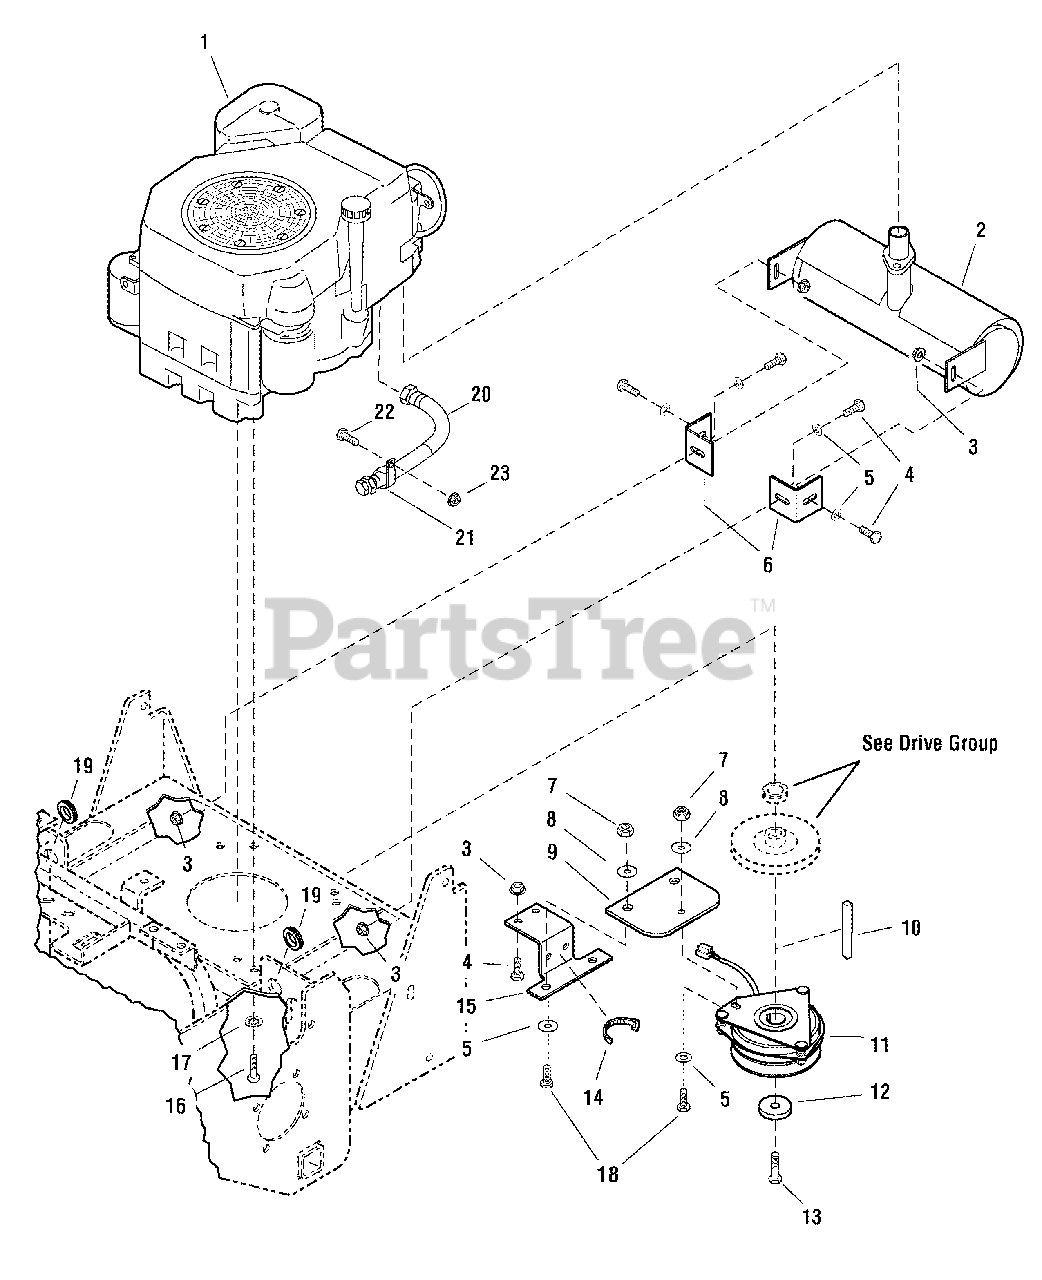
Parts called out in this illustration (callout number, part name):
3	NUT, Hex Serrated Flange, 5/16-18
4	CAPSCREW, Hex Head, 5/16-18 X 3/4
5	WASHER, SAE, 5/16
6	BRACKET, Muffler Support, Orange
6	BRACKET, Muffler Support, Red
7	NUT, Hex Nylon Lock, 5/16-18
8	WASHER, Clutch Anchor, 5/16
9	PAD, Clutch Anchor
10	KEY, 1/4 Square X 2-1/4
11	CLUTCH, Electric
12	SPACER, .45 X 1.62 X .37
13	BOLT, CRANKSHAFT, 7/16-20 X 3-1/4"
15	CLUTCH ANCHOR, Orange
15	CLUTCH ANCHOR, Red
16	BOLT, M8-1.25 X 30 MM
17	WASHER, 5/16 Internal Tooth Lock
18	CAPSCREW, Hex Head, 5/16-18 X 1
19	GROMMET, 3/4"
20	HOSE, Oil Drain
21	CLAMP, Vinyl Insulated
22	BOLT, 1/4-20 x 3/4
23	NUT, 1/4-20 Hex, Serrated Flange
